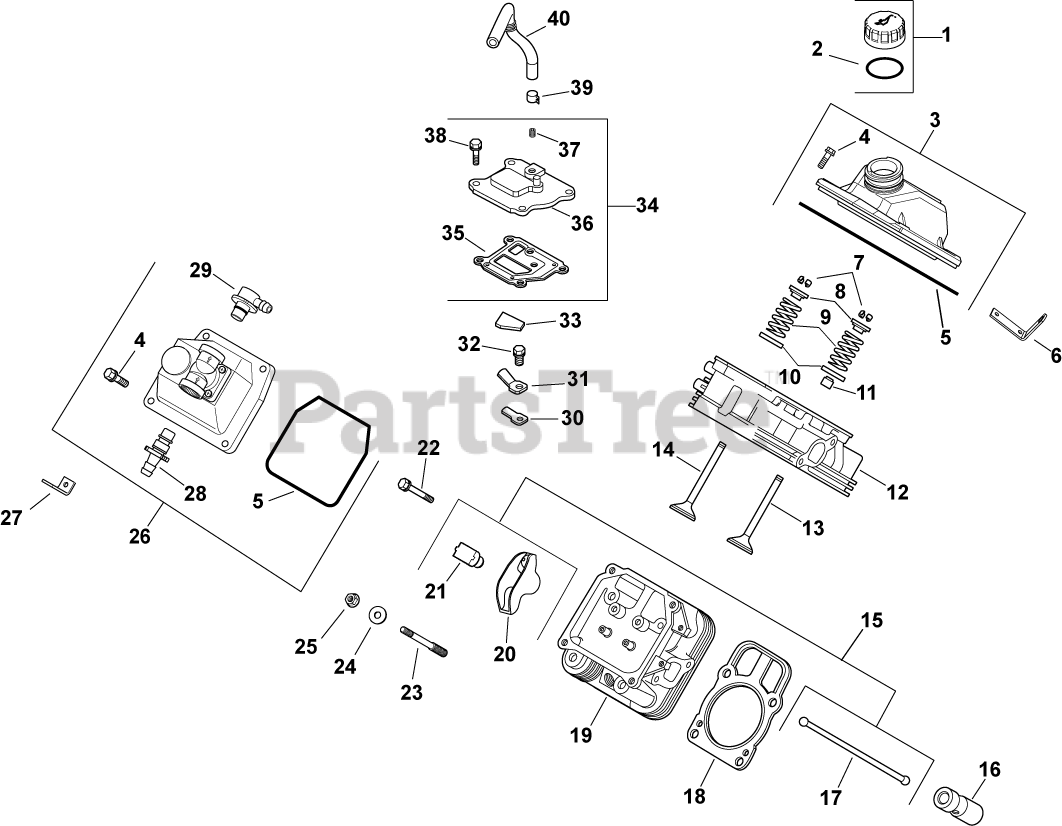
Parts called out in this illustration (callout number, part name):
1	KIT, OIL FILL CAP (YELLOW)
2	O-RING, DIPSTICK
3	KIT, VALVE COVER-OIL FILL
4	SCREW, FLG M6X1.0X30
5	O-RING (YELLOW), VALVE COVER
6	STRAP, LIFTING-USE 25 445 03-S
7	KIT, RETAINER
8	RETAINER, VALVE SPRING - USE 25 173 28-S
9	SPRING, VALVE
10	RETAINER, SPRING
11	SEAL, VALVE STEM - (#2503214S)
12	HEAD, SERVICE ASSY CYL #1-USE 24 318 106
13	VALVE, INTAKE (STD)
14	VALVE, EXHAUST (STD) - USE 32 016 01-S
15	KIT, VALVE TRAIN
16	LIFTER, HYDRAULIC VALVE-USE 25 351 10-S
17	ROD, PUSH
18	CYL HEAD GASKET KIT-USE 24 841 04-S
19	HEAD, SERVICE ASSY CYL #2-USE 24 318 114
20	ARM, ROCKER
21	PIVOT, ROCKER ARM
22	SCREW, ROCKER ARM PIVOT-USE M-640034-S
23	STUD, M8X1.25
24	WASHER, FLAT 8.6 MM
25	NUT, FLG M8X1.25
26	KIT, VALVE COVER-FUEL PUMP
28	KIT, STRAIGHT FITTING
29	KIT, 90 DEG. FITTING
30	RETAINER, REED
31	REED, BREATHER
32	SCREW, FLG THD FRM M5X.8X10
33	FILTER, BREATHER
34	KIT, BREATHER ASSEMBLY
35	GASKET, BREATHER-USE 24 041 67-S
36	COVER, BREATHER -USE 24 033 01-S
37	PLUG, CTSK PIPE 1/8"
38	SCREW,FLG THD FRM M6X1.0X20-(#25086396S)
39	CLAMP, BAND SPRING HOSE-(#2523737S)
40	HOSE, BREATHER
2401602-S	VALVE, EXHAUST (.25)
2401702-S	VALVE, INTAKE (.25)
